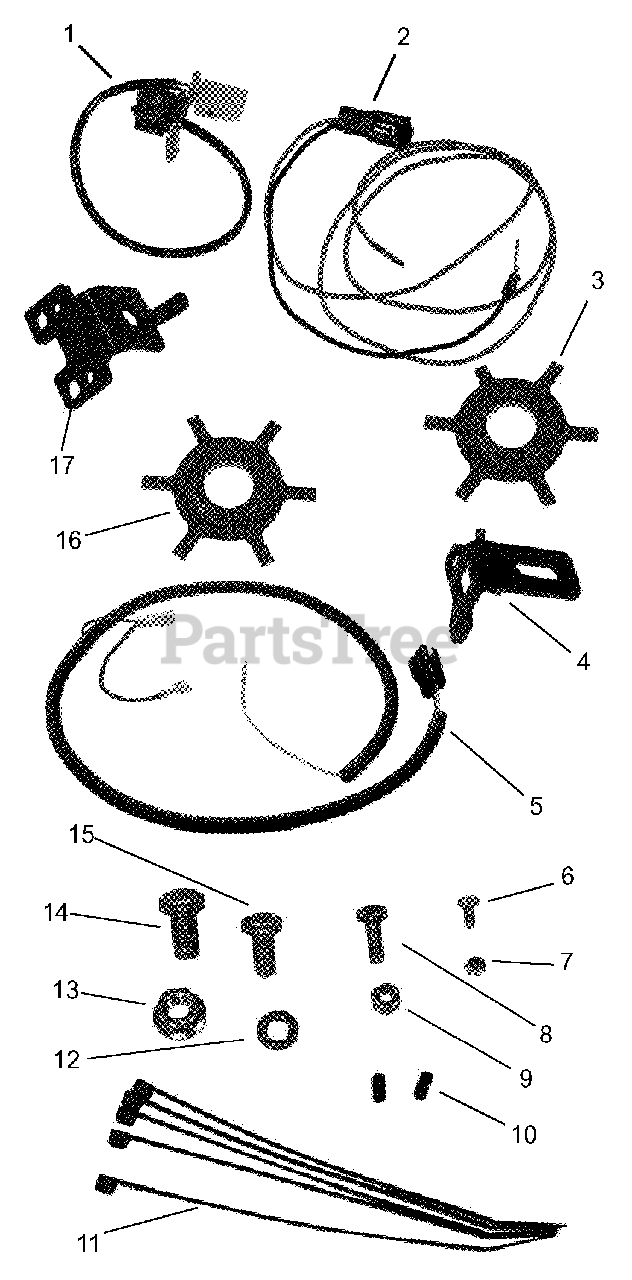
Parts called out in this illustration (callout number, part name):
1	Eye-Q Engine RPM Sensor
2	Diesel RPM Sensor Harness
3	6T RPM Sprocket 1-3/4 I.D.
4	RPM Sensor Mounting Bracket
5	RPM Sensor Harness
6	Hex Bolt, M4 x 0.7 x 12 mm
7	Nylon Lock Nut M4-0.7
8	Hex Bolt, M6-1 x 16 mm
9	Nylon Lock Nut, M6-1
10	Set Screw, 10-24 x 3/8 UNC-3A
11	Cable Tie, 5-1/2
12	Lock Washer, 5/16 x 5/64
13	Top Locking Flange Nut, 3/8-16
14	Hex Bolt, 3/8-16 x 3/4
15	Hex Bolt, M8-1.25 x 16
16	6T RPM Sprocket, 1-5/8 I.D.
17	RPM Sensor Mounting Bracket
